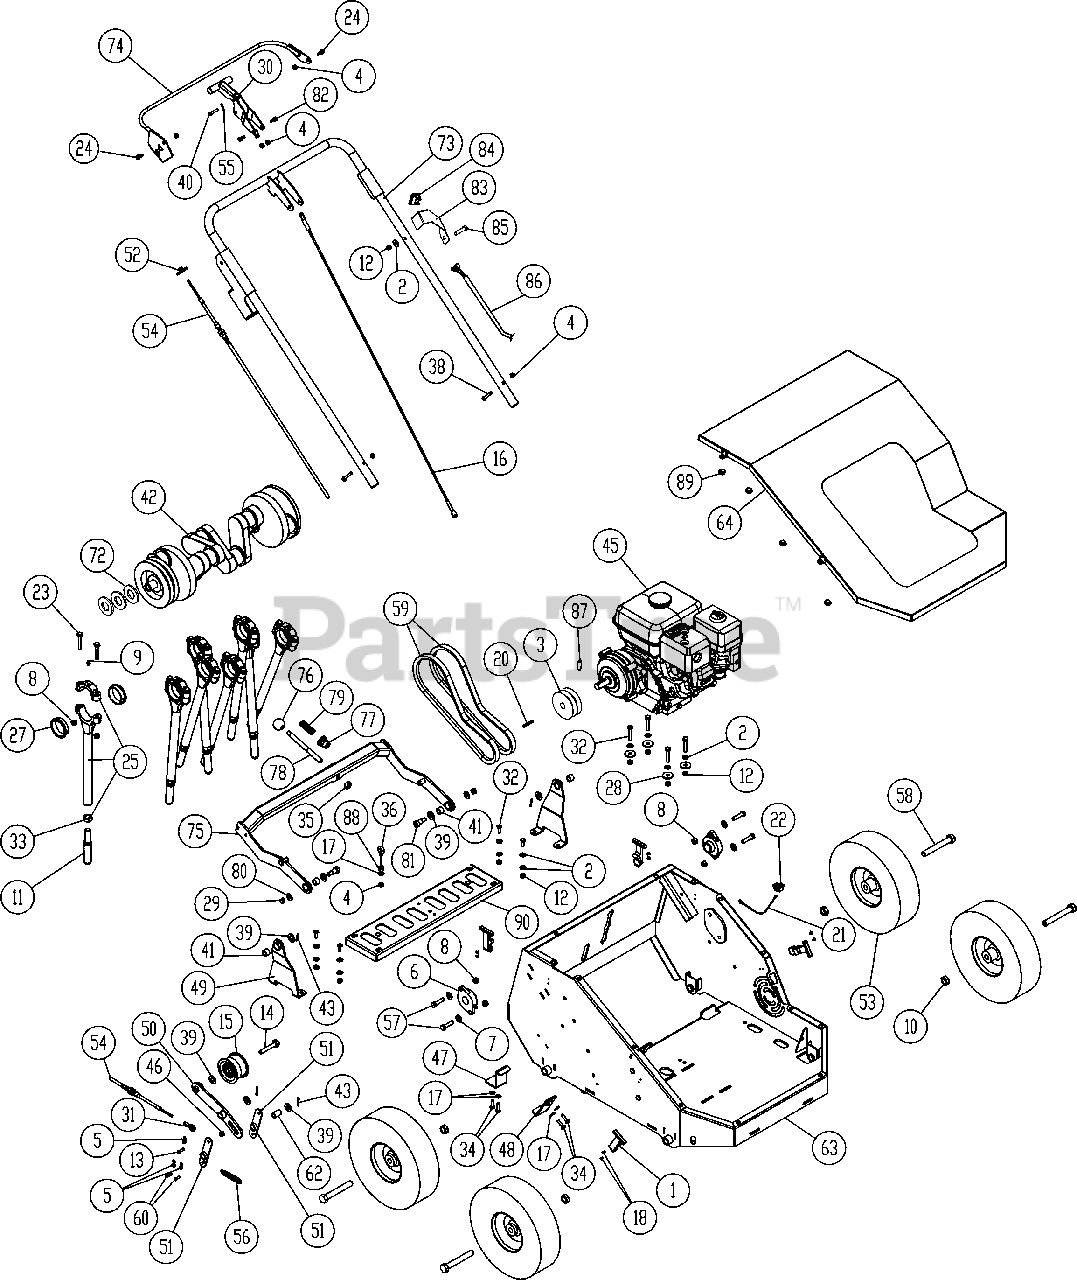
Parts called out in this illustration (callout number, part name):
1	RUBBER LATCH KIT
2	WASHER 5/16" FLAT
3	ENGINE PULLEY 3.5 DIA
4	NUTLOCK 1/4"-20 HEX ZP
5	1/4" RUE RING
6	CARTRIDGE BEARING 1"
7	WASHER 3/8" FLAT
8	NUTLOCK 3/8"-16 HEX
9	GREASE FITTING 1/4"-28
10	NUT JAM 5/8"-11 2 WAY LOCKNUT ZP
11	TINE 5/8"
12	NUTLOCK 5/16"-18 HEX ZP
13	CLEVIS PIN 1/4" X 3/4"
14	SCREWCAP 1/2"-13 X 2 GR5 ZP
15	IDLER PULLEY 2.75 X 1.50 DIA
16	RETRACTER PLATE CABLE
17	WASHER 1/4" FLAT
18	STAINLESS RIVET 1/8" X 1/4"
20	KEY 3/16" X 2 1/8"
21	WIRE HARNESS PL HOOD SWITCH
22	SWITCH INTERLOCK
23	SHCS 3/8"-16 X 2" BLK OX
24	SHOULDER BOLT 5/16" X 3/8"
25	KIT KEYED TINE ROD AND CAP
27	JOURNAL BEARING 2"
28	FENDER WASHER 5/16"
29	LOCK NUT 3/8"-16 HEX
30	RETRACTOR HANDLE
31	SPHERICAL ROD END 10-32 UNF
32	SCREWCAP 5/16"-18 X 1 3/4" HCS ZP
33	NUT JAM 5/8"-11 ZP
34	SCREWCAP 1/4"-20 X 3/4" GR 5 HCS ZP
35	NUTLOCK 1/2"-13 HEX ZP
36	EYEBOLT 1/4"-20
38	SCREWCAP 1/4"-20 X 1 3/4" HCS ZP
39	WASHER 1/2" FLAT
40	CLEVIS PIN 1/4" X 1 1/8"
41	BUSHING 1/2" ID X 3/4" OD X 1/2"
42	8 TINE CRANKSHAFT
43	COTTER PIN 1/8" X 1"
45	GX160 HONDA ENGINE W/GEARBOX
46	PREHARD ROLLER
47	BRACKET BELT FINGER LOWER PL25
48	BRACKET BELT FINGER UPPER PL25
49	RETRACTOR PLATE ARM
50	ARM IDLER W/BUSHINGS PL2500SPH
51	CLUTCH CAM ARM
52	CABLE ADJUSTMENT SPOOL
53	WHEEL 12" W 5/8" BEARING HUB
54	PUSH PULL CABLE 55"
55	COTTER PIN 3/32 X 3/4"
56	EXTENSION SPRING 1/2" X 3" - 5"
57	SCREWCAP 3/8"-16 X 1 1/2" HCS ZP
58	SCREWCAP 5/8"-11 X 4 1/2" HCS ZP
59	COGGED V BELT B 35"
60	CLEVIS PIN 3/16" X 3/4"
62	BUSHING 1/2" UD X 5/8" OD X 1"
63	800 SERIES FRAME
64	COVER WA PL2500SP
72	MACHINERY BUSHING 1" X 1 1/2 X 14 GA
73	HANDLE WA PL25 12 GA
74	800 SERIES CLUTCH LEVER
75	ADJUSTABLE RETRACTOR YOKE
76	PHENOLIC BALL KNOB
77	ADJUSTABLE RETRACTOR LOCK PLUG
78	RETRACTOR ADJUSTMENT LEVER
79	SPRING .72 X 2" -.6"
80	WASHER 5/16" USS THRU-HARDENED ZINC YELLOW
81	SHOULDER BOLT 1/2" X 5/8"
82	SHOULDER BOLT 5/16" X 1/4"
83	SWITCH LKG RKR
84	BRACKET MOUNT SWITCH
85	SCREWCAP 5/16"-18 X 1 1/2" GR 5 HCS ZP
86	HARNESS WIRE 60"
87	SCREW SET 3/8"-16 X 3/4" CUP POINT TORQUE TO 22-24 FT-LBS.
88	ROLLER 0.5" OD X 0.25 ID X 0.313
89	RUBBER BUMPER PUSH IN
90	8 TINE RETRACTOR PLATE
